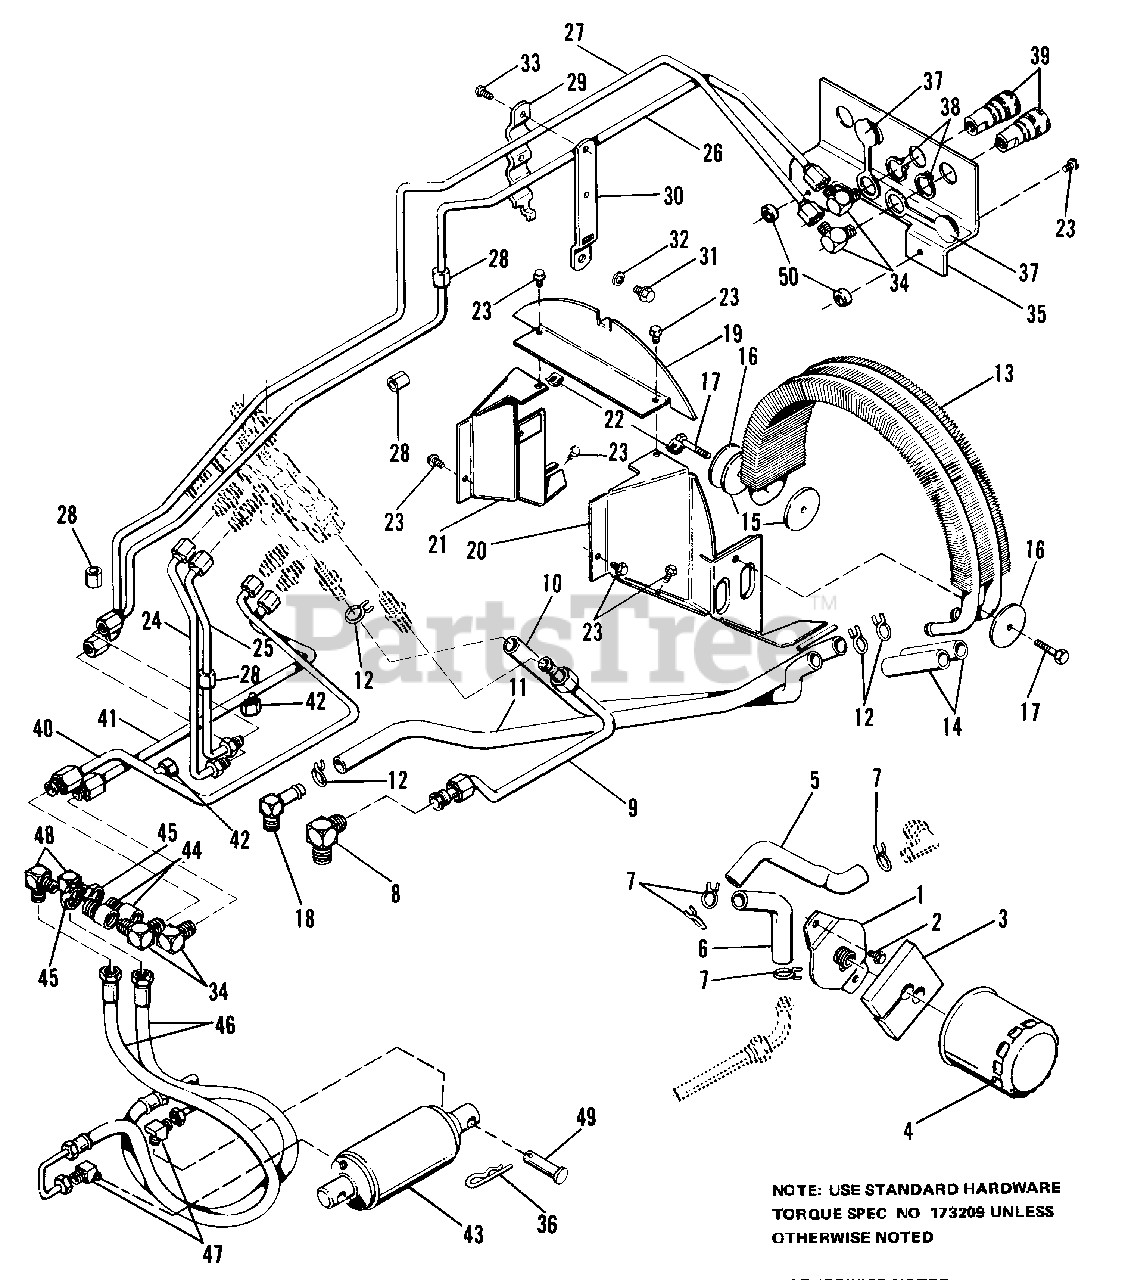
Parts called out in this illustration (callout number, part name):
1	PLATE ASSY
2	SCREW, Tapping, 5/16-18 x 1/2
5	HOSE, Hydro
6	HOSE, Hydro
7	CLAMP, Hose
8	ELBOW, 90ø
9	TUBE ASSY
10	HOSE, Hydro
11	HOSE, Hydro
12	CLAMP, Hose
13	COOLER, Oil
15	WASHER, Rubber
17	SCREW, Taptite, 1/4-20 x 1-1/2
18	ELBOW, 90ø
19	SHROUD ASSY, Upper Rear
20	SHROUD ASSY, R.H.
21	SHROUD ASSY, L.H.
22	NUT, Speed, 1/4 20
23	SCREW, Tapping, 1/4 20 x 1/2
24	TUBE ASSY
25	TUBE ASSY
26	TUBE ASSY
27	TUBE ASSY
31	CAPSCREW, Hex, 3/8-16 x 5/8
32	LOCKWASHER, 3/8
33	SCREW, Taptite, 1/4-20 x 5/8
35	PLATE, Mounting
36	CLIP, Spring
37	PLUG, Plastic
38	RING, Retaining
40	TUBE ASSY
41	TUBE ASSY
45	LOCKNUT, Hex, 7/8-14
